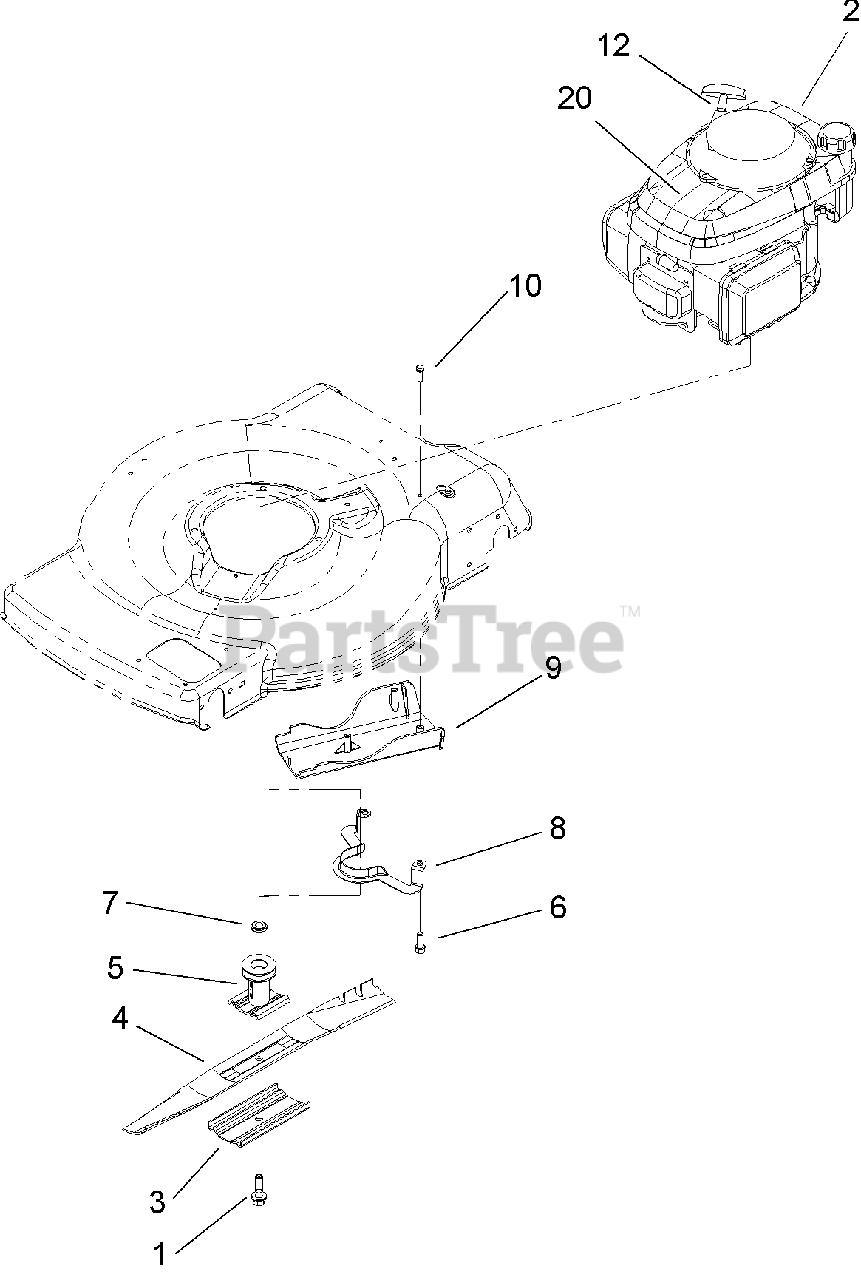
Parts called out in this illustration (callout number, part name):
1	BOLT-BLADE
3	Support-Blade
4	BLADE-22 INCH
5	BLADE DRIVER ASM
6	SCREW-TAPTITE
7	Spacer-Driver
9	Cover-Belt, Rear
10	SCREW-HWH
12	STOP-ROPE
20	DECAL-RECOIL
